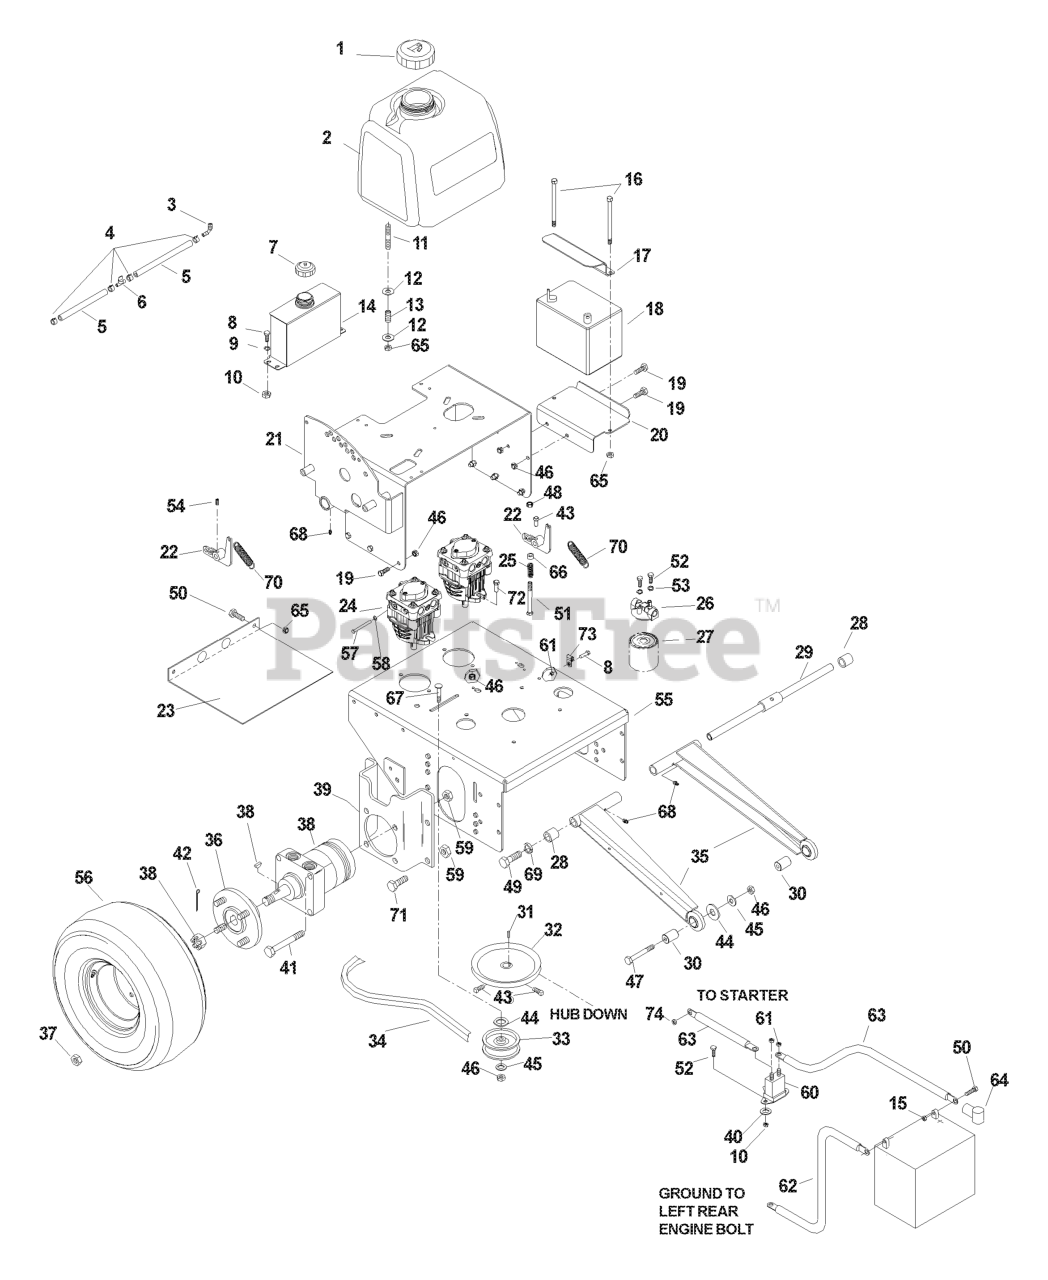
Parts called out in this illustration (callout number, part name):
1	FUEL CAP ANTI-SPLASH
3	HOSE BARB 90 DEGREE
4	HOSE CLAMP
5	GAS LINE 10"
6	FUEL VALVE
7	HYDRAULIC CAP
8	HCS 1/4C X 3/4 HCS
9	WASHER 1/4 FLAT
10	NUT 1/4C CENTER LOCK
11	STUD, 5/16C
12	WASHER 5/16 FLAT
14	OIL TANK BLK
15	NUT 5/16C CENTERLOCK
16	BOLT - 5/16 X 7
17	BATTERY STRAP
18	BATTERY, 12 V 330 AMP
19	SCREW 3/8C X 3/4 HEX CAP
20	BATTERY TRAY
21	TANK SUPPORT
22	PUMP ARM WELDMENT
23	LOWER BELT SHIELD
24	HG_PUMP
26	FILTER HEAD
27	HYDRAULIC OIL FILTER
29	STRUT SHAFT
30	FRONT SPACER
31	KEY 5 MM SQ X 25 MM
33	IDLER PULLEY
34	TRANSMISSION BELT
35	STRUT WELDMENT
36	HUB.WHEEL.ZTR
37	LUG NUT 1/2F
38	WHEEL MOTOR
39	MOTOR MOUNT
40	WASHER 1/4 INT TOOTH
41	HCS 1/2C X 2 3/4
42	COTTER PIN
43	SCREW 5/16C X 5/8 SQ HEAD
44	WASHER 1/2 FLAT
45	WASHER 3/8 FLAT
46	NUT 3/8C CENTERBLOCK
47	HCS 3/8C X 2 1/4
48	NUT 3/8-16 NYLOC
49	HHCS 1/2-13 X 1
50	HCS 5/16C X 3/4
51	HEX SCREW 3/8-20 X 2.75
52	HCS 1/4C X 5/8
53	LOCKWASHER 1/4"
54	5/16C X 5/8 "V" POINT
55	REAR DECK ORANGE PAINTED
56	TIRE/WHEEL ASSY
56	TIRE.TURF.SAVER.18X7.5-8
56	VALVE STEM TR-412
56	WHEEL
57	CLEVIS PIN
58	NUT PUSH
59	NUT 1/2-13 HEX NYLOC ZD
61	NUT.1/4-20.HEX.NYLOC.ZD
62	CABLE-NEGATIVE
63	CABLE POSITIVE, LONG
65	NUT 5/16 NYLOC
67	RHSNB 3/8C X 2
68	ZERK
69	WASHER 1/2" SPLIT LOCK
70	SPRING-TRANS
71	HCS 1/2C X 1 1/4 SERRATED HEAD
72	4CS 3/8C X 1 SERRATED HEAD
73	DOUBLE TUBE CLAMP
74	JAM NUT 1/4C (2 2 PW01)
